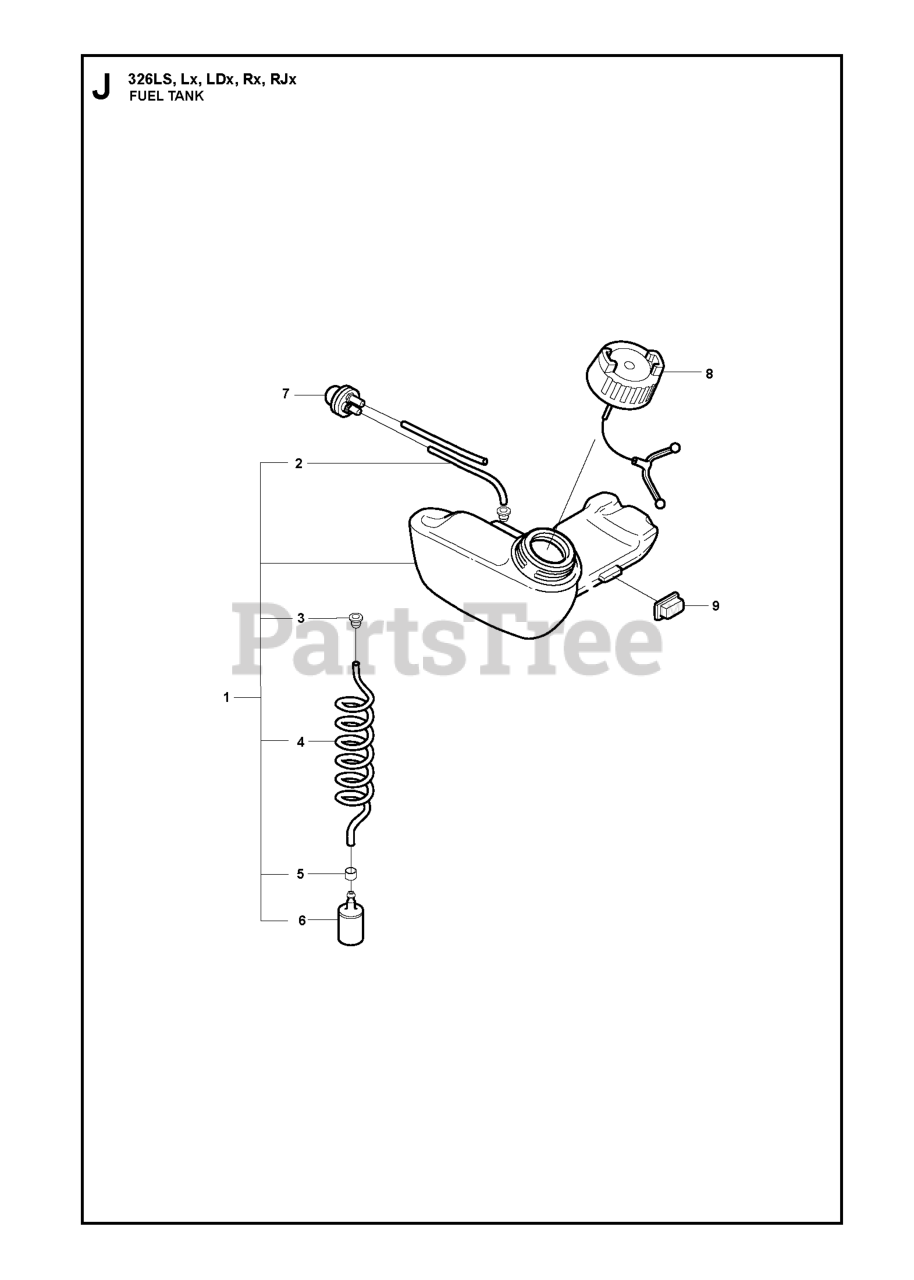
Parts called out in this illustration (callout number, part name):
2	HOSE.FUEL L=102
3	FUEL TANK BUSHING
4	FUEL HOSE
5	HOSE CLAMP
6	RP FUEL FILTER
7	AIR PURGE BUBBLE
8	TANK CAP
